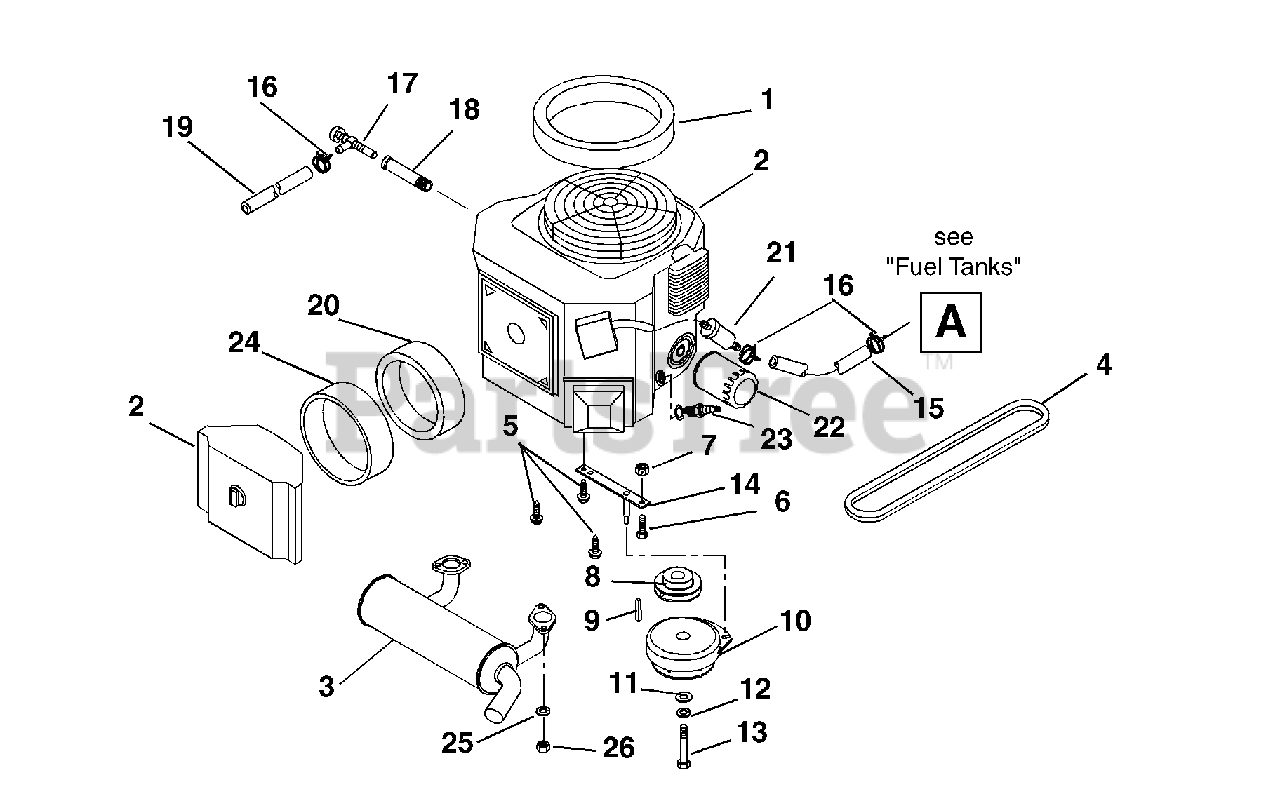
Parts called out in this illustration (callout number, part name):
1	Seal-Foam
2	25HP-Kohler Command Vertical
2	Engine, 25 HP Kawasaki
2	Engine, Kawasaki 19HP
2	Engine, Kawasaki 23HP
3	Muffler, Kohler Command
3	Muffler- Kawasaki
4	V-Belt, A-Section 28.29 x .531
5	Screw-Tapping Hex-Washer-Head .38-16 x 1.00
6	Bolt-Hex .31-18 x 1.75 Grade 5
7	Nut-Locking-Center .31-18
8	Pulley-4.46 DIA x 1.12 Bore
9	Key-Square .25 x 1.00 x .25
10	Electric Clutch
11	Washer-Flat-Steel .515 x 1.625 x .250
12	Washer-Locking .44 x .109
13	Bolt-Hex .44-20 x 3.00 Grade 5
14	Anchor-Clutch
15	Gas Line-Bulk 1/4" ID
16	Hose-Clamp
17	Cock-Oil Drain
18	Adapter-Oil Drain
19	Gas Line-Bulk 1/4" ID
20	Air Filter
21	Fuel Filter
22	Oil Filter
23	Spark Plug
24	Element, Precleaner
24	Element, Pre-Cleaner
25	Washer-Lock .31 x .078 Regular
26	Nut-Hex M8-1.25
